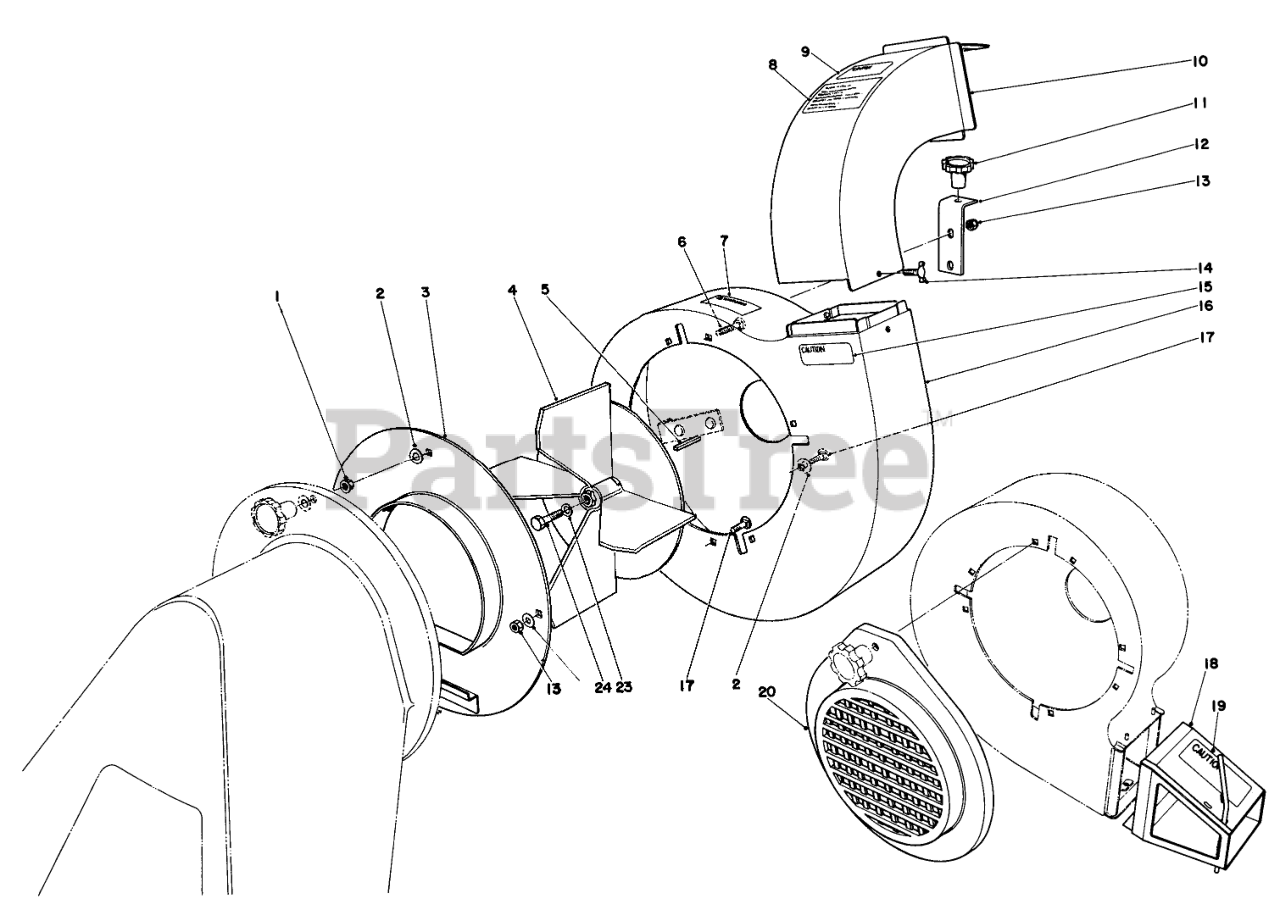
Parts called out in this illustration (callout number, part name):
1	NUT-FLANGE
2	WASHER-FLAT
3	Blower Cover
4	Fan
5	KEY-SQUARE
6	BOLT-CARR
7	ROTATE WARNING DECAL
8	TORO ADVER DECAL
9	DECAL CAUTION BAG
10	Chute-Vacuum
12	Bracket-Housing
13	NUT-LOCK, CONE
14	1/4 - 20 3/4 WING SCR
15	WARNING DECAL
16	Blower Housing
17	SCREW-CARR
18	Blower Exhaust (Incl. Ref. #19)
19	EXHAUST DECAL
20	INTAKE-BLOWER
23	WASHER-LOCK
24	SPEC SCREW
